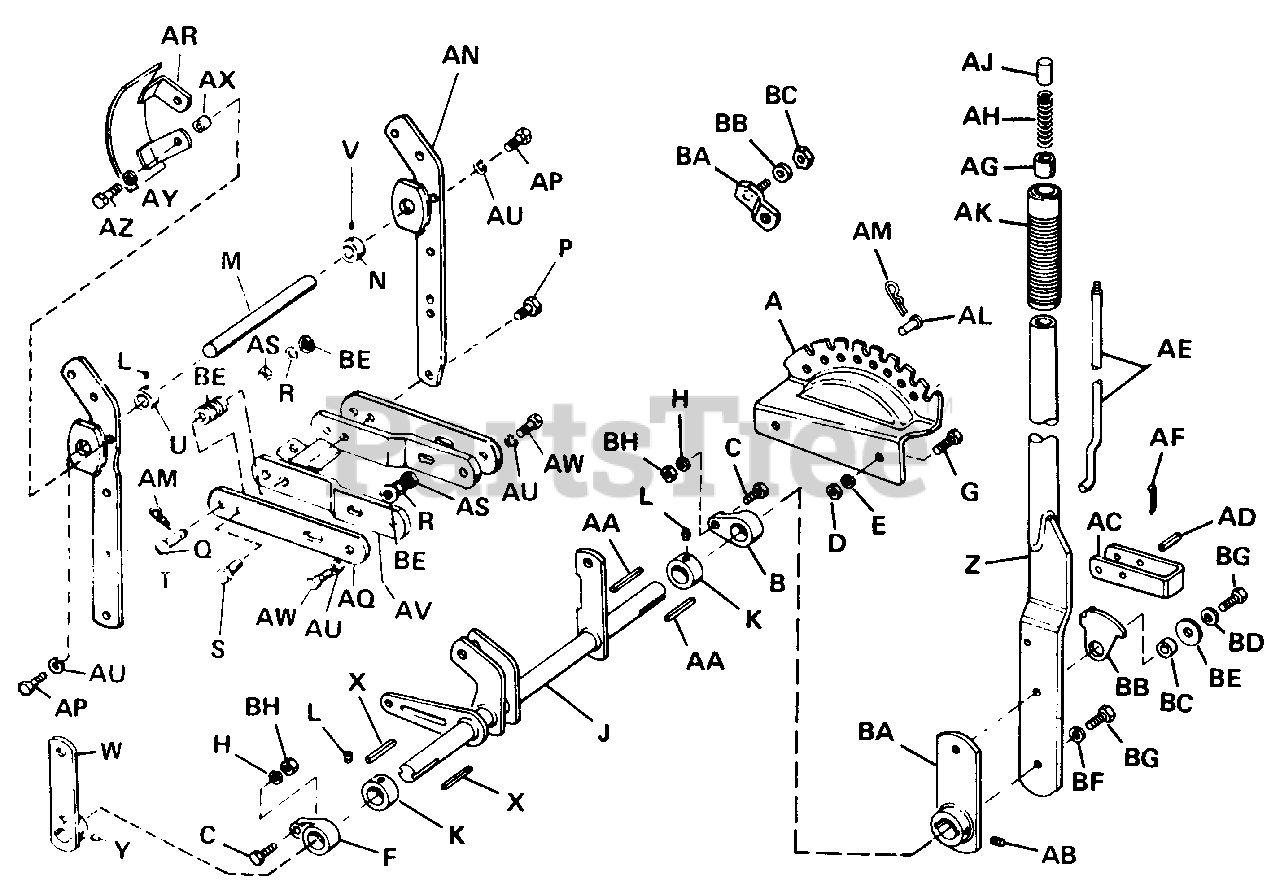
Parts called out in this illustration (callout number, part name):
A	Lift Lever Quadrant
B	Lift Lever Bearing
C	Hex Cap Screw, 5/16"-18" x 1-1/4"
D	Full Hex Nut, 5/16"
E	Lock Washer, 5/16"
F	Lift Lever Bearing
G	Hex Capscrew, 3/8"-16 x 3/4"
H	Lock Washer, 3/8"
J	Lift Shaft Assy.
K	Set Collar
L	Set Screw 5/16"-18 x 5/16"
P	Hex Capscrew, 7/16"-14 x 1-1/2"
Q	Round Head Pin
R	Lockwasher
S	Hex Capscrew, 7/16"-14 x 1-3/4"
T	Arm Assy.
U	Set Collar
V	Set Screw, 5/16"-18 x 1/2"
W	Front Lift Lever Assy.
Y	Set Screw, 5/16"-18 x 1/4"
Z	Lift Lever Assy.
AB	Set Screw, 5/16"-18 x 1/4"
AC	Lift Lever Latch
AE	Latch Rod
AF	Cotter Pin, 3/32" x 3/4"
AJ	Thumb Button
AK	Handle Grip
AM	Spring Clip
AN	Arm Assy.
AP	Hex Capscrew, 7/16"-14 x 1"
AR	Pulley Guard Assy.
AS	Full Hex Nut, 7/16"
AU	Lock Washer, 7/16"
AV	Draw Bar Assy.
AW	Hex Capscrew, 7/16"-14 x 1-1/4"
AY	Lockwasher, 7/16"
AZ	Hex Capscrew, 7/16"-14 x 1-1/2"
BA	Pivot Bar Assy.
BB	Plain Washer, 3/8"
BC	Hex Nut, 3/8"-16
